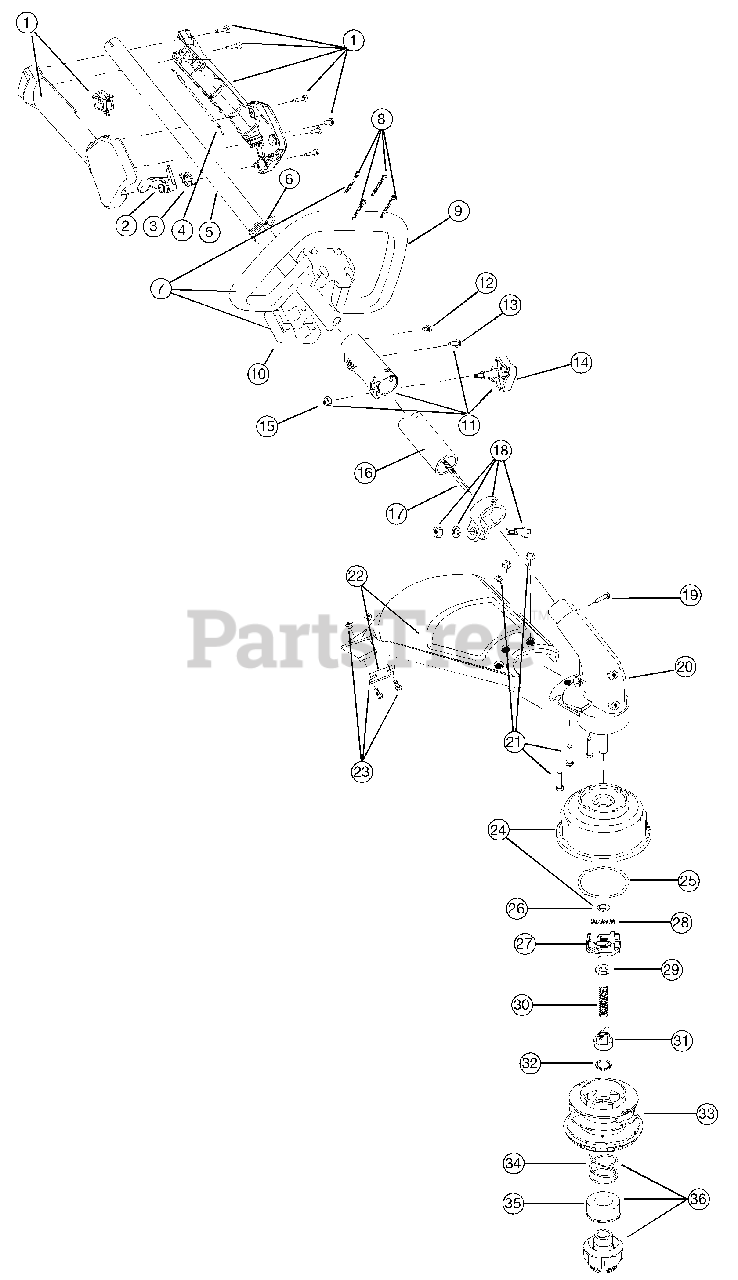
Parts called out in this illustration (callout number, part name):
1	Throttle Housing and Trigger Assembly (includes 2 & 3)
2	Throttle Trigger
3	Throttle Trigger Spring
4	Throttle Cable Assembly
5	Upper Drive Shaft Housing Assembly
6	Harness Clip
7	Deluxe D-Handle Assembly (includes 8-10)
9	Deluxe D-Handle
10	Bottom Clamp
11	EZ-Link(TM) Coupler (includes 12-15)
14	Adjustment Knob
15	Knob Retaining Bolt
16	Lower Drive Shaft Housing Assembly
17	Lower Flexible Drive Shaft
18	Lower Clamp Assembly (includes 19)
19	Anti-Rotation Screw
20	Gear Box Assembly (includes 18, 24-36)
21	Shield Mounting Hardware
22	Shield and Blade Assembly
23	Blade Assembly
24	Outer Spool and Eyelet Assembly w/Retainer
26	Thrust Washer
28	Small Spring
33	Inner Reel
34	Large Spring
36	Bump Head Knob Assembly w/Spring & Foam Seal
